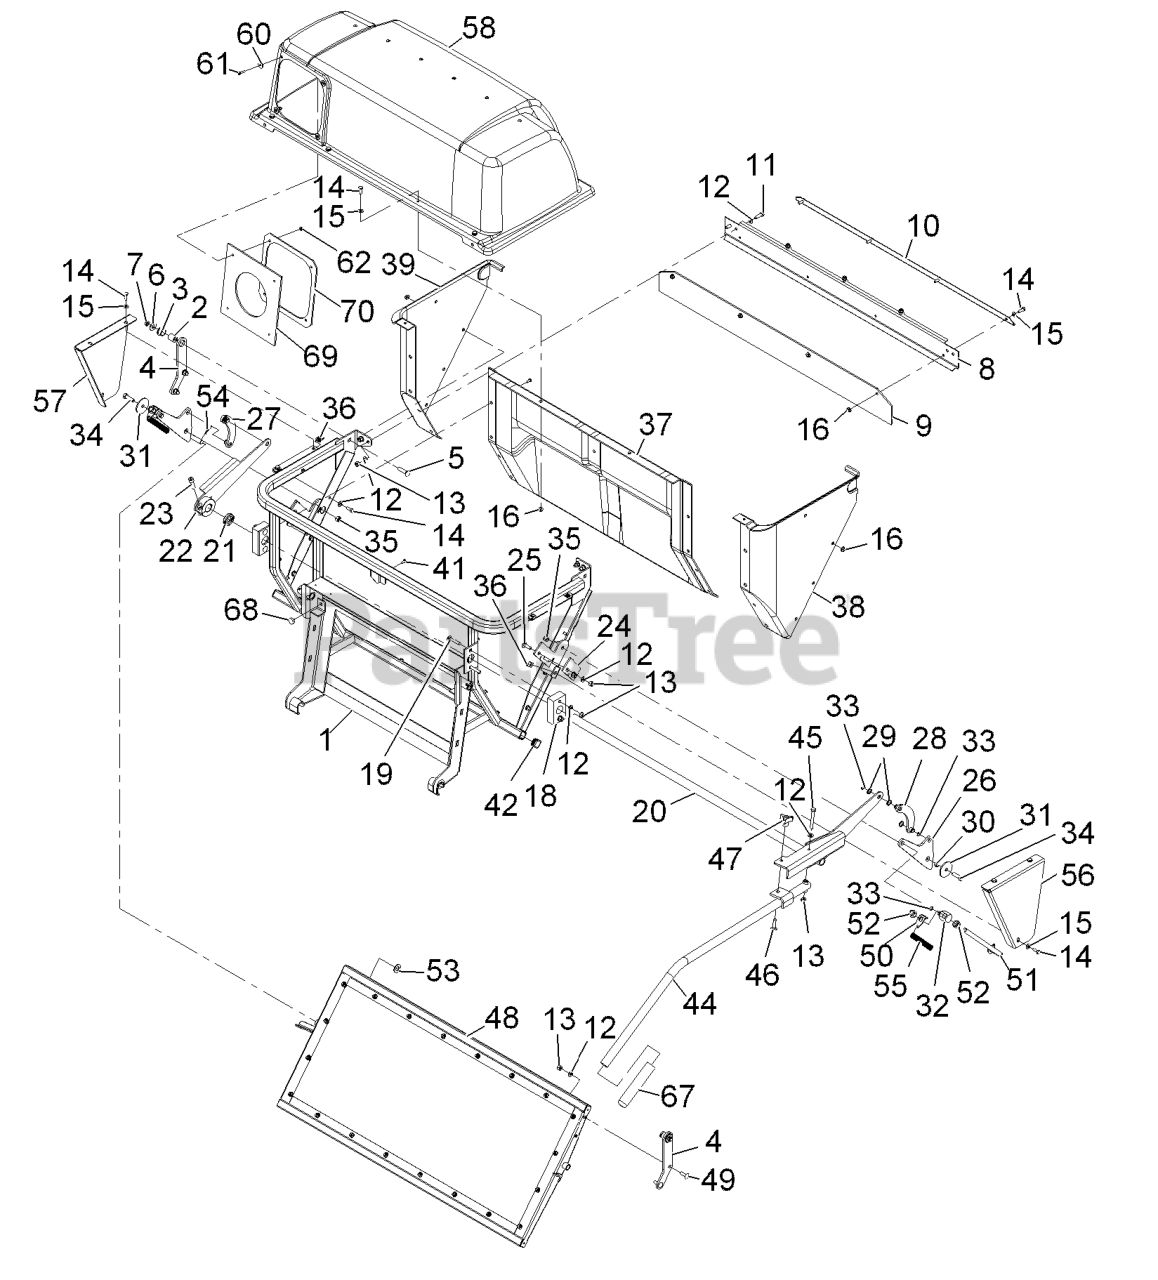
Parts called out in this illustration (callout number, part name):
1	Frame ASM
2	Pin-Pivot, Hinge
3	Bearing
4	Plate, Hinge
5	Bolt-Carriage 3/8-16 X 1 1/2
6	Washer-3/8 Std
7	Nut-Nyloc 3/8-16 Thin
8	Plate-Rear
9	Seal-Door
10	Strap-Hold Down
11	Screw-HH 5/16-18 X 1
12	Washer-5/16 SAE
13	Nut-Nyloc 5/16-18
14	Screw-HH 1/4-20 X 3/4
15	Washer-1/4 SAE
16	Nut-Whizlock 1/4-20
18	Bearing
19	Bolt-Carriage 5/16-18 X 1 3/4
20	Bellcrank
21	Shaft-Collar
22	Link
23	Screw-Sh 3/8-16 X 1 1/4
24	Stop-Linkage
25	Bolt-Carriage 5/16-18 X 1
26	Arm-Linkage, Door
27	Link-RH
28	Link-LH
29	Washer-Nylon
30	Bearing-Linkage, Pivot
32	Trunnion-Link
33	Ring-Retaining
34	Screw-HH 3/8-16 X 1 1/4
35	Nut-Nyloc 3/8-16
36	Nut-Retainer-Panel 1/4-20
37	Panel-Bagger
38	Panel-Bagger, LH
39	Panel-Bagger, RH
44	Handle-Qd7
45	Screw-HH 5/16-18 X 2 1/2
46	Bolt-Carriage 5/16-18 X 1 1/4
47	Knob-3 Prong
48	Asm, Door
49	Bolt-Carriage 5/16-18 X 1 Sp
50	Anchor-Spring
51	Link-Door
52	Nut-Hex 1/2-20
53	Washer-1/2 SAE
54	Hairpin-Cotter
58	Asm, Hood
61	Screw-PPH #10-24 X 7/8
62	Nut-Nyloc #10-24
67	Handle-Grip
69	Seal-Chute
70	Clamp-Seal
